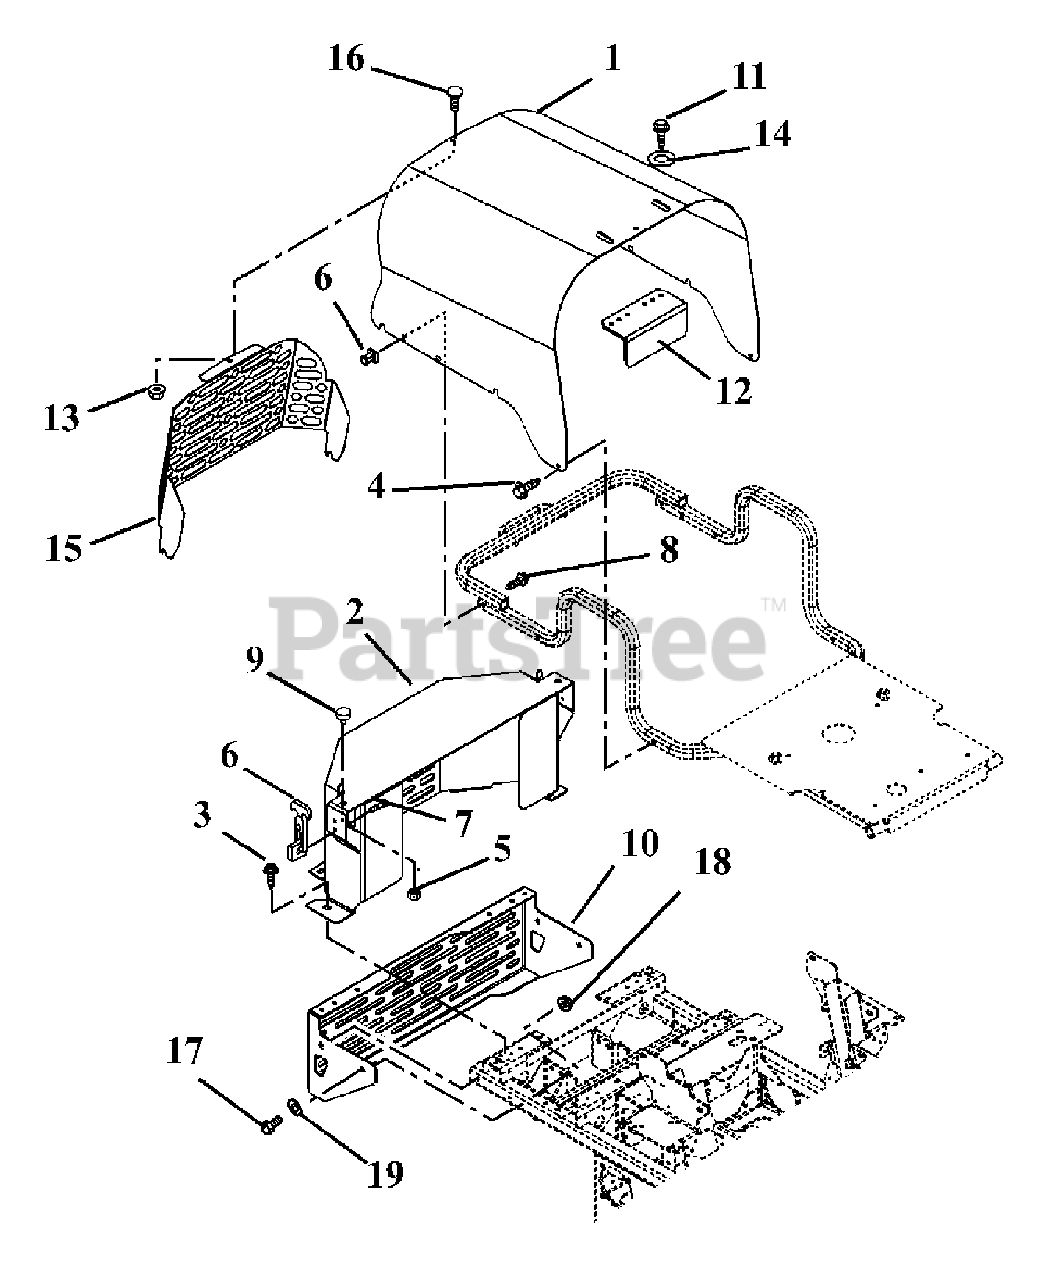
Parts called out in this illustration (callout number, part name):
1	L/C HOOD - RED
2	DIESEL BELT GUARD - BLACK
3	@SCR-TAP .38-16X.75 HWH TR YWZ
4	@SCR-TAP .38-16X.50 HWH TR YWZ
5	@NUT-SPNLK-FLG .312-18 YWZC
6	LATCH, RUBBER
7	@SCR-MCH 10-24X.50 HWH YWZC
8	@SCR-MCH 10-24X1.50 HWH YWZC
9	BUMPER, RUBBER
10	WMT,REAR DIESEL BUMPER-GRAVELY
11	@SCR-TAP .25-20X.50 HWH TR YWZ
12	GUARD, RADIATOR CAP
13	@NUT-LK-TOP-FLG .25-20 YWZC
14	@WSHR-FL-STL.281X.62X.065 YWZC
15	L/C HOOD GUARD - BLACK
16	@BLT-RDHDSQNK .25-20X.50 G5YZ
17	@BLT-HEX .38-16X2.75 GR5 YWZC
18	@NUT-LK-TOP-FLG .38-16 YWZC
19	@WSHR-FL-STL.406X.812X.065 YWZ
